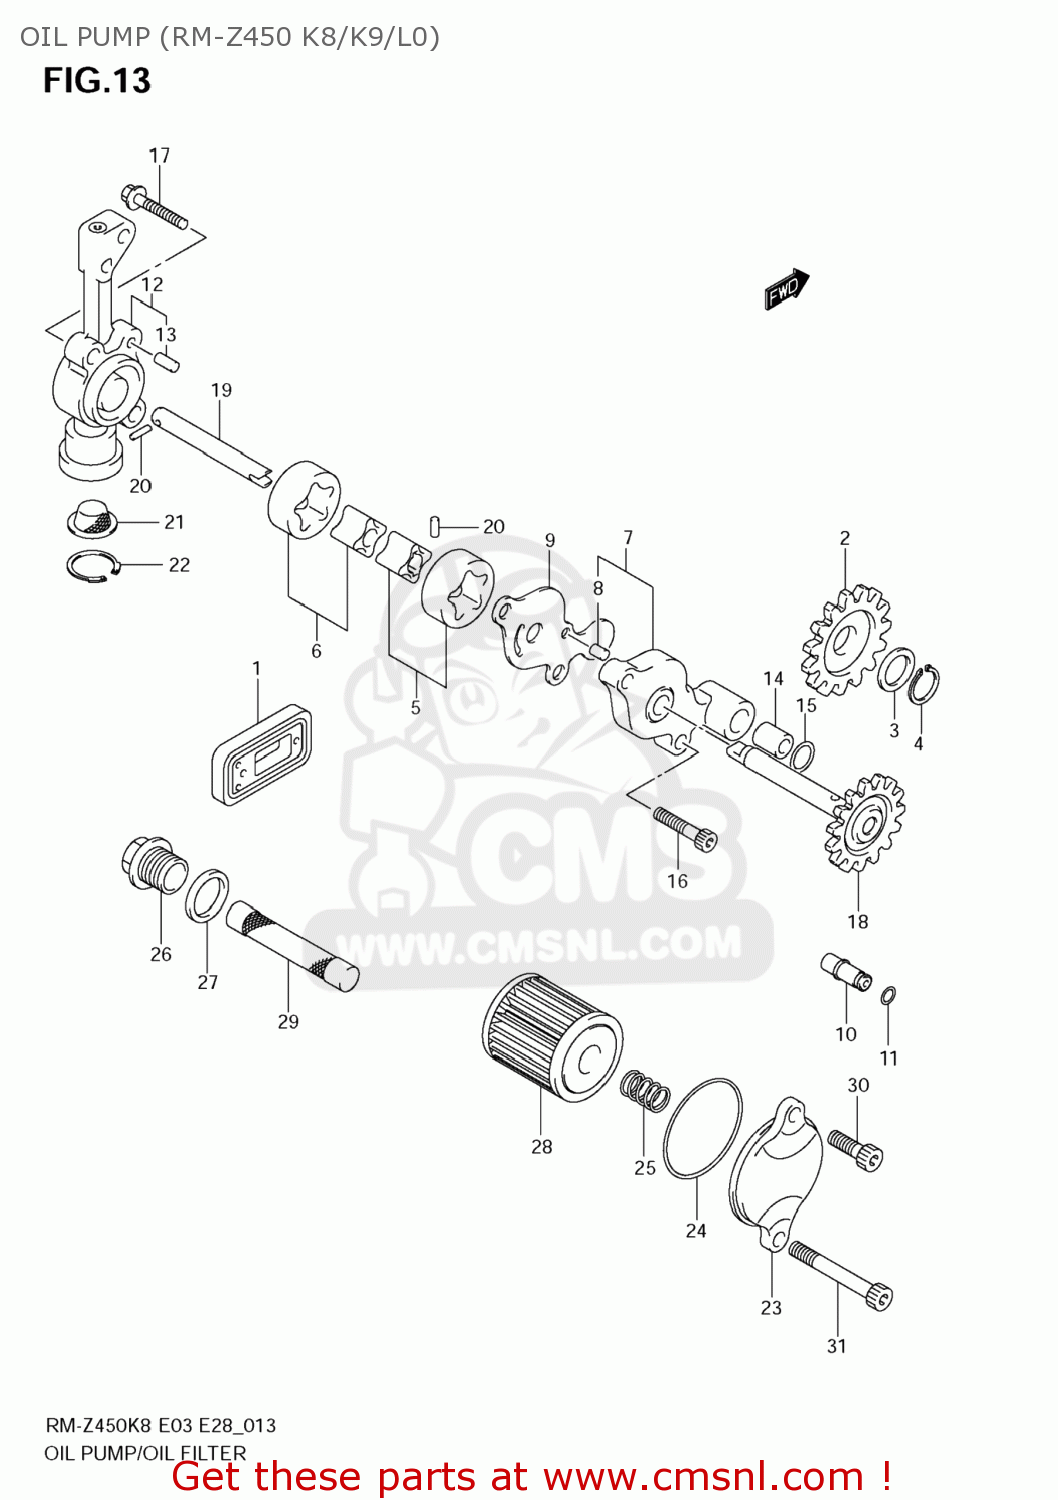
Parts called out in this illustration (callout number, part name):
1	VALVE ASSY,OIL REED
2	GEAR,OIL PUMP IDLE
3	SHIM(12X18X0.5)
4	CIRCLIP
5	ROTOR SET,OIL PUMP NO.1
6	ROTOR SET,OIL PUMP
7	COVER,OIL PUMP NO.1
8	PIN
9	PLATE,OIL PUMP NO.1
10	VALVE ASSY,OIL RELIEF
11	O RING(D:1.2,ID:4.7)
12	COVER,OIL PUMP NO.2
13	PIN
14	PIN
15	O RING(D:1.9,ID:8.6)
16	BOLT
17	BOLT(6X25)
18	SHAFT,OIL PUMP DRIVEN GEAR
19	SHAFT,OIL PUMP NO.2
20	PIN(2.5X11.8)
21	STRAINER,OIL PUMP NO.2
22	CIRCLIP
23	CAP,ENG OIL FILTER OUTER
24	O RING(D:2,ID:38.5)
25	SPRING
26	CAP,ENG OIL STRAINER
27	GASKET(16X22X2) (NAS)
28	FILTER ASSY,ENGINE OIL
29	STRAINER,ENGINE OIL
30	BOLT(6X16)
31	BOLT
